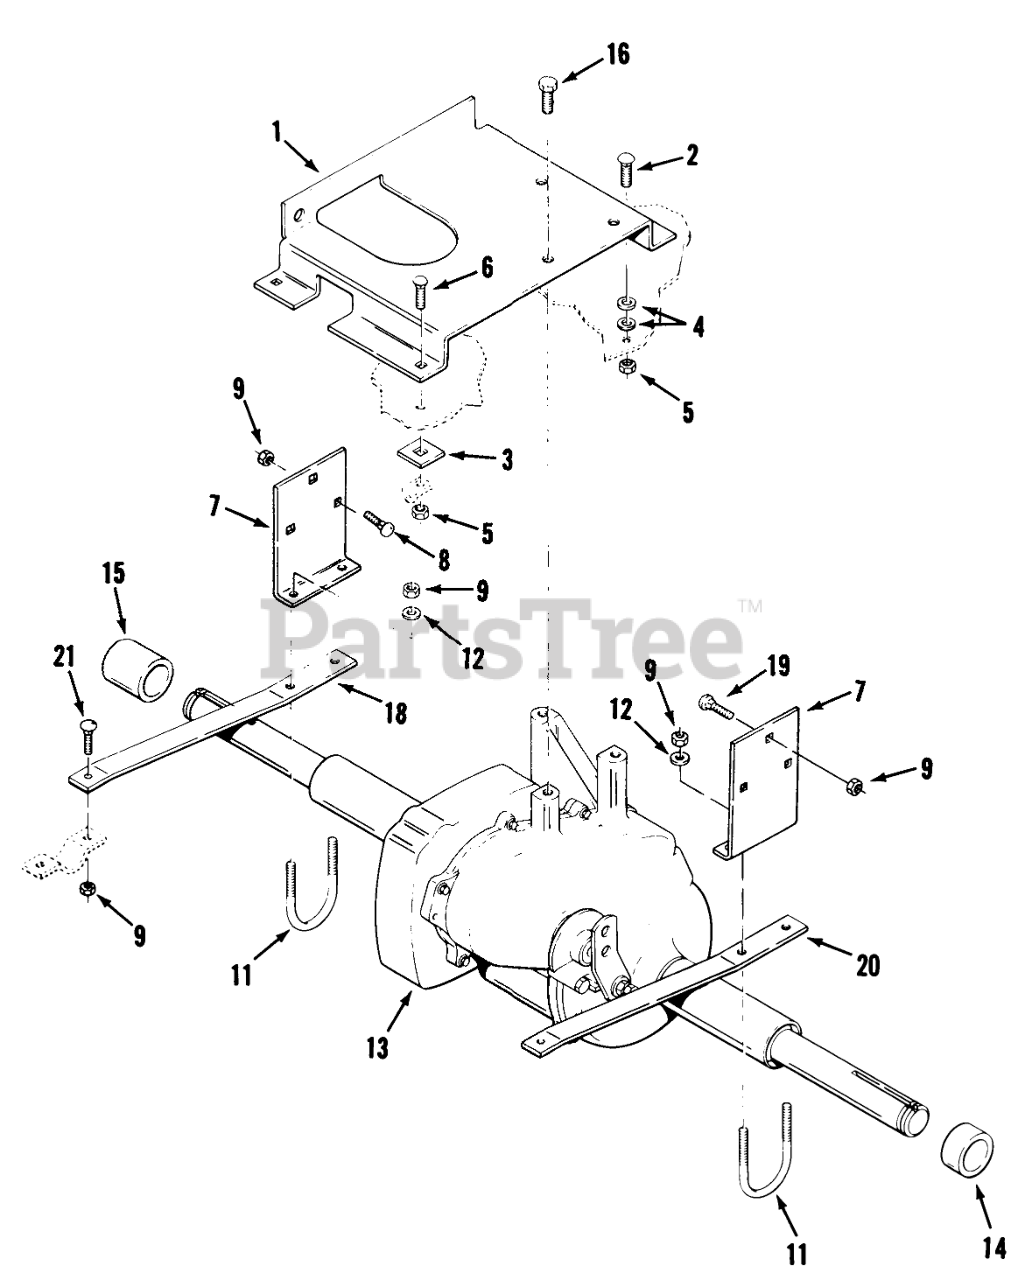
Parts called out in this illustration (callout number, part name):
1	Differential Support
2	Bolt-Carriage
3	PAD-SHORT R
4	WASHER 5/16 SAE
5	Nut
6	Bolt-Carriage
7	BRACKET-MOUNTING R
8	Bolt
9	Nut
11	U-BOLT AXLE MTG
12	WASHER 5/16 SAE
13	Sleeve
14	SPACER-AXLE LH
15	Axle Spacer RH
16	Bolt
18	BRACE FRAME
20	BRACE FRAME
21	Bolt-Carriage
